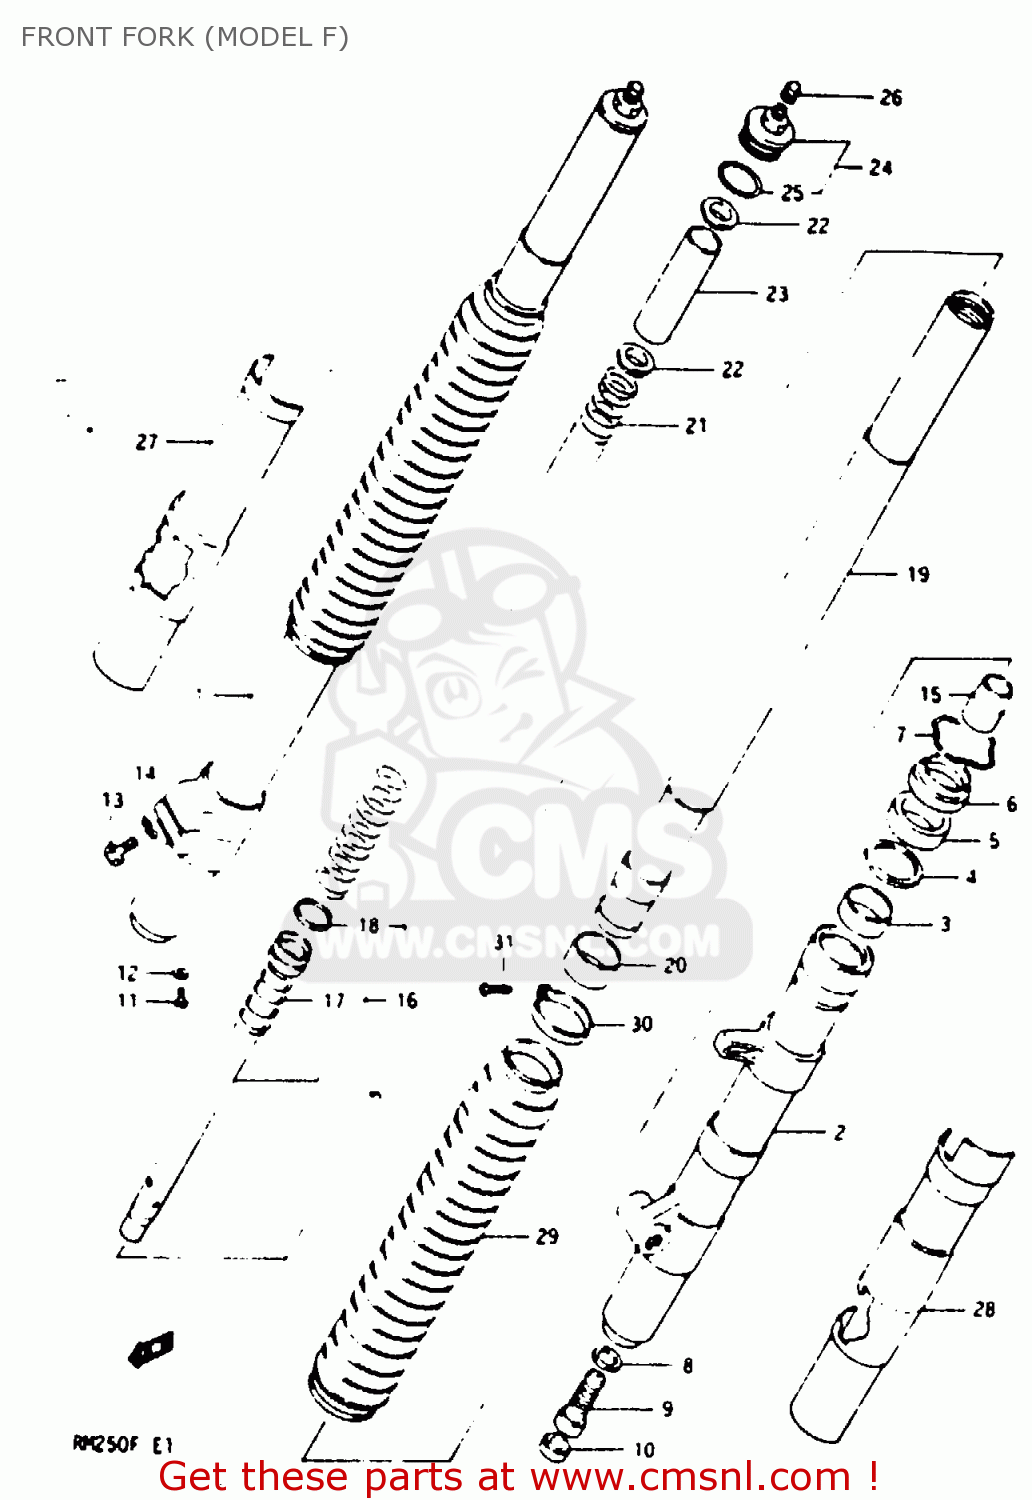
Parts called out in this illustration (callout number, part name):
1	TUBE,OUTER,RIGHT
2	TUBE,OUTER,LEFT
3	METAL,SLIDE
4	WASHER
5	SEAL,OIL
6	SEAL,DUST
7	RING,STOPPER
8	GASKET,FORK CYLINDER
9	VALVE,DF
10	CAP,FRONT FORK DF
11	SCREW 4X6
12	GASKET,DRAIN,PLUG (NAS)
13	BOLT (8X30)
14	WASHER,LOCK,8.
15	PIECE,FRONT FORK OIL LOCK
16	CYLINDER
17	SPRING,REBOUND
18	RING,FRONT FORK PISTON
19	TUBE,FORK,INNER
20	PISTON
21	SPRING,FRONT FORK
22	GUIDE,FRONT FORK SPRING
23	SPACER,FRONT FORK SPRING
24	CAP,FORK INNER TUBE
25	O RING
26	CAP
27	PROTECTOR,RIGHT
28	PROTECTOR,LEFT
29	BOOT,FRONT FORK COVER
30	BAND,BOOT,UPPER
31	SCREW 4X10
